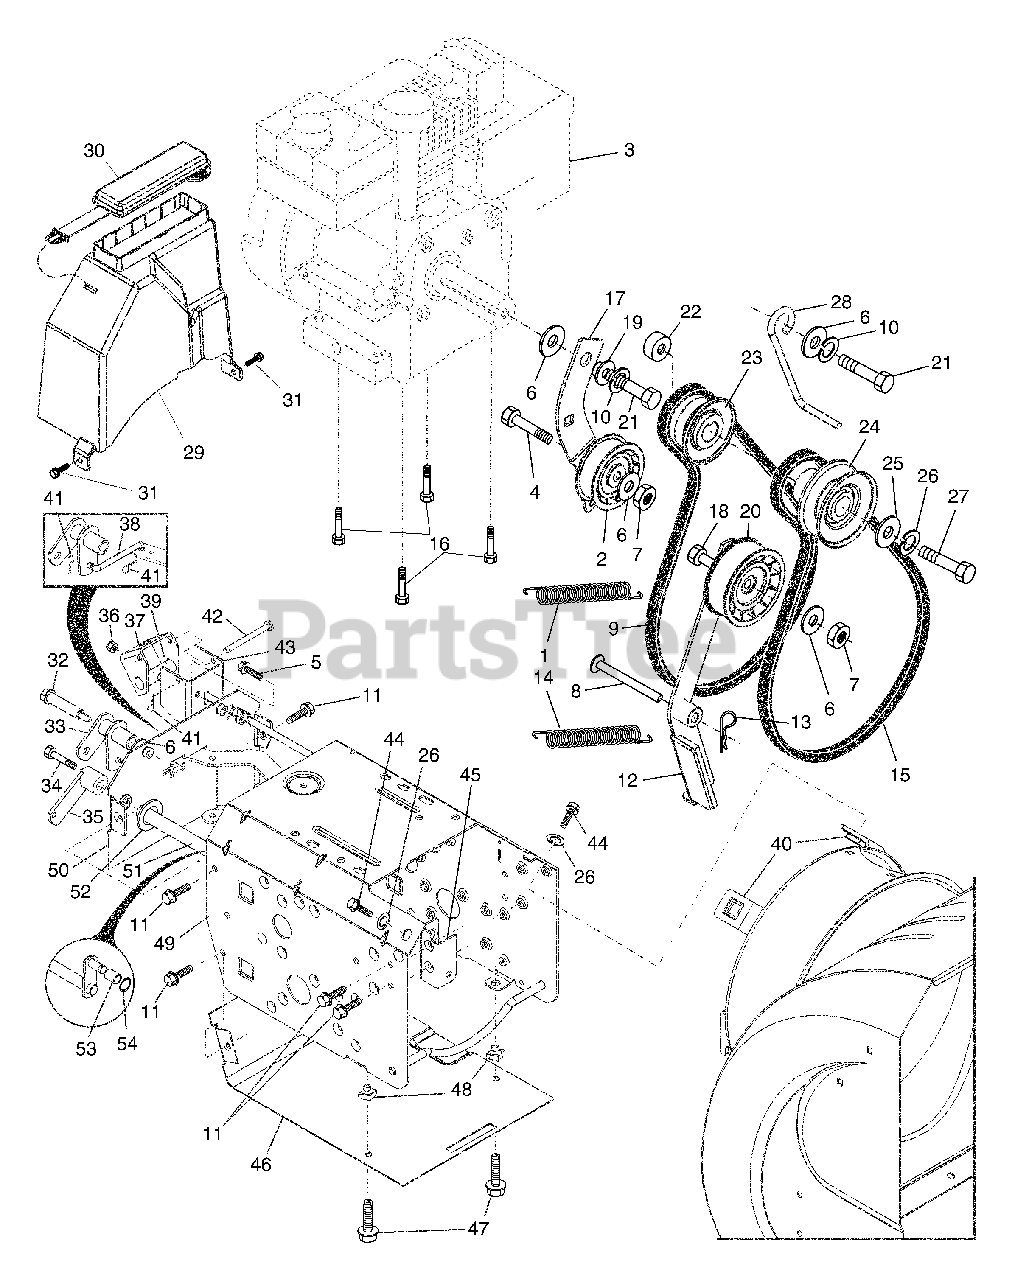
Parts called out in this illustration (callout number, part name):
1	Spring, Traction Idler
2	Pulley, Idler (2-1/4)
4	Screw, Hex Head 5/16-18 x 1-1/4
5	Screw, Hex Washer Head 5/16-18 x 3/4
6	Washer, Flat
7	Nut, Jam, Lock 5/16-18
8	Pin, Idler Pivot
9	V-Belt, Traction Drive
10	Washer, Lock 5/16
11	Screw, Hex Head 5/16-18 x 1/2
12	Impeller Idler Arm Assembly
13	Retainer, Hairpin
14	Spring, Brake
15	V-Belt, Impeller Drive
16	Screw, Hex Head 3/8-16 x 1-1/4
17	Arm, Idler
18	Screw, Hex Head 5/16-18 x 1-1/2
19	Bushing, Idler Pivot
20	Pulley, Idler (2-3/4)
21	Screw, Hex Head 5/16-24 x 1
22	Spacer, Engine Pulley
23	Pulley, Engine, Traction Drive
24	Pulley, Engine, Impeller Drive
25	Washer, Flat 3/8
26	Washer, Lock, Helical
27	Screw, Hex Head 3/8-24 x 1-3/8
28	Guide, Belt
29	Cover, Belt
30	Cover, Toolbox
31	Screw, Hex Head 1/4-20 x 1/2
32	Bolt, Shoulder 5/16-18
33	Bellcrank Shifter
34	Screw, Hex Head 1/4-28 x 3/4
35	Arm, Auger Control
36	Nut, Lock 5/16-18
37	Bellcrank Assembly
38	Link, Speed Control
39	Trunnion, Clutch
40	Nut, Cage 3/8-16
41	Hairpin, Cotter 3/32 x 1/2
42	Pin, Bellcrank
43	Bracket, Bellcrank
44	Screw, Hex Head 3/8-16 x 1-1/2
45	Pivot Bracket, Impeller Idler Arm
46	Pan, Frame Bottom
47	Screw, Hex Head 5/16-18 x 3/4
48	Nut, Speed 5/16-18
49	Frame Assembly
50	Plate, Frame End
51	Shaft, Auger Control
52	Washer, Hardened
53	Roller
54	Ring, Retaining
